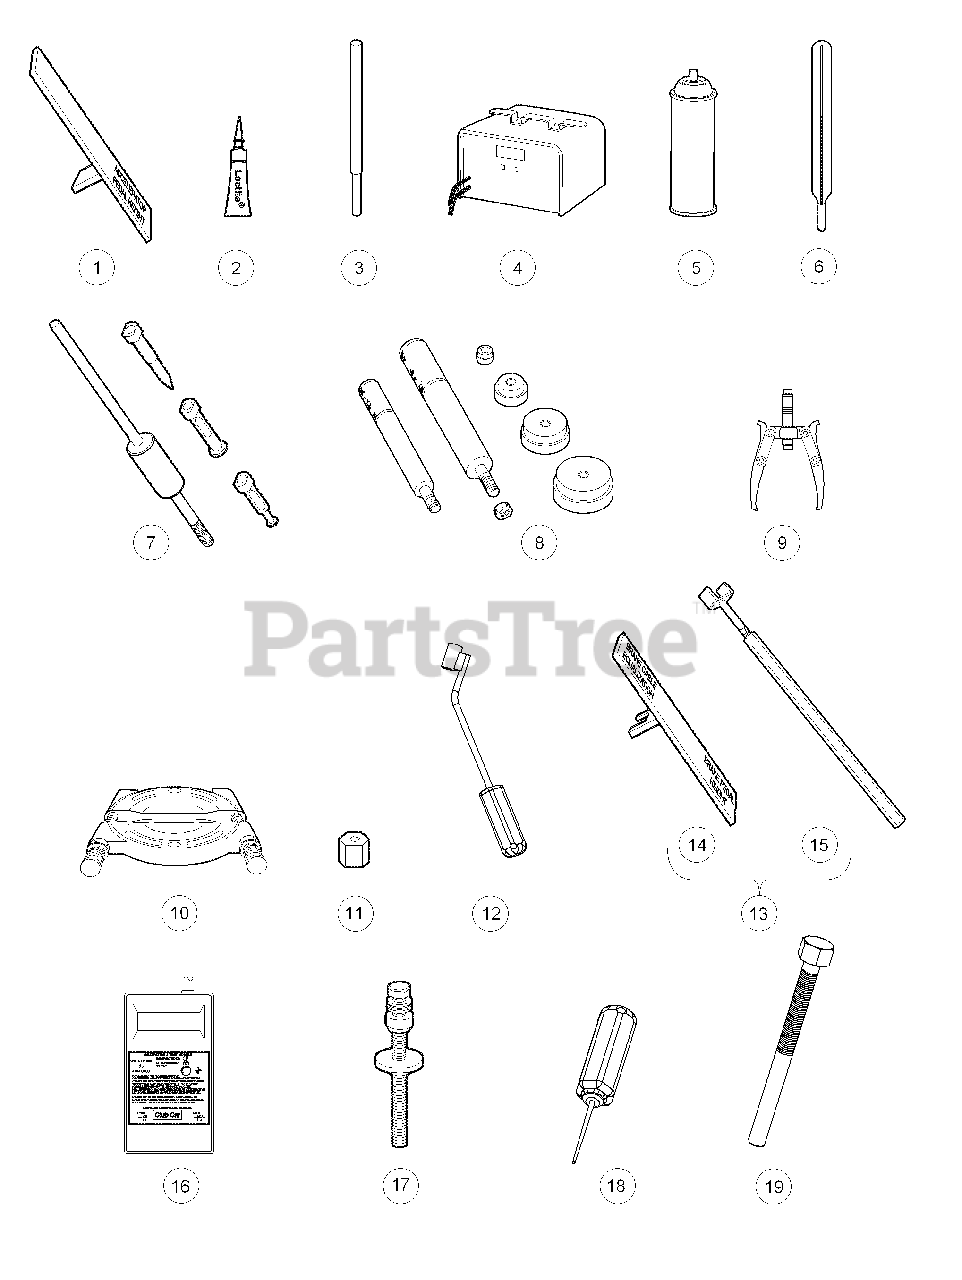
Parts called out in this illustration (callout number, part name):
1	Accelerator Pedal Adjustment Tool
2	Adhesive, Guide Ring, 3-Gram Tube
4	Battery Discharge Machine, 36/48 Volt
5	Battery Terminal Protector Spray
6	Battery Thermometer
7	Bearing and Oil Seal Remover Assembly
8	Bearing Driver Set
9	Bearing Puller
10	Bearing Puller Wedge Attachment
11	Brake Adjustment Tool
12	Brake Cable Release Tool
13	Brake Pedal Adjustment Tool Kit
14	Brake Pedal Adjustment Tool
15	Brake Pedal Tension Tool
16	Calibration Test Module
17	Cam Installation Tool
18	Charger Bezel Tool
19	Clutch Removal Tool
